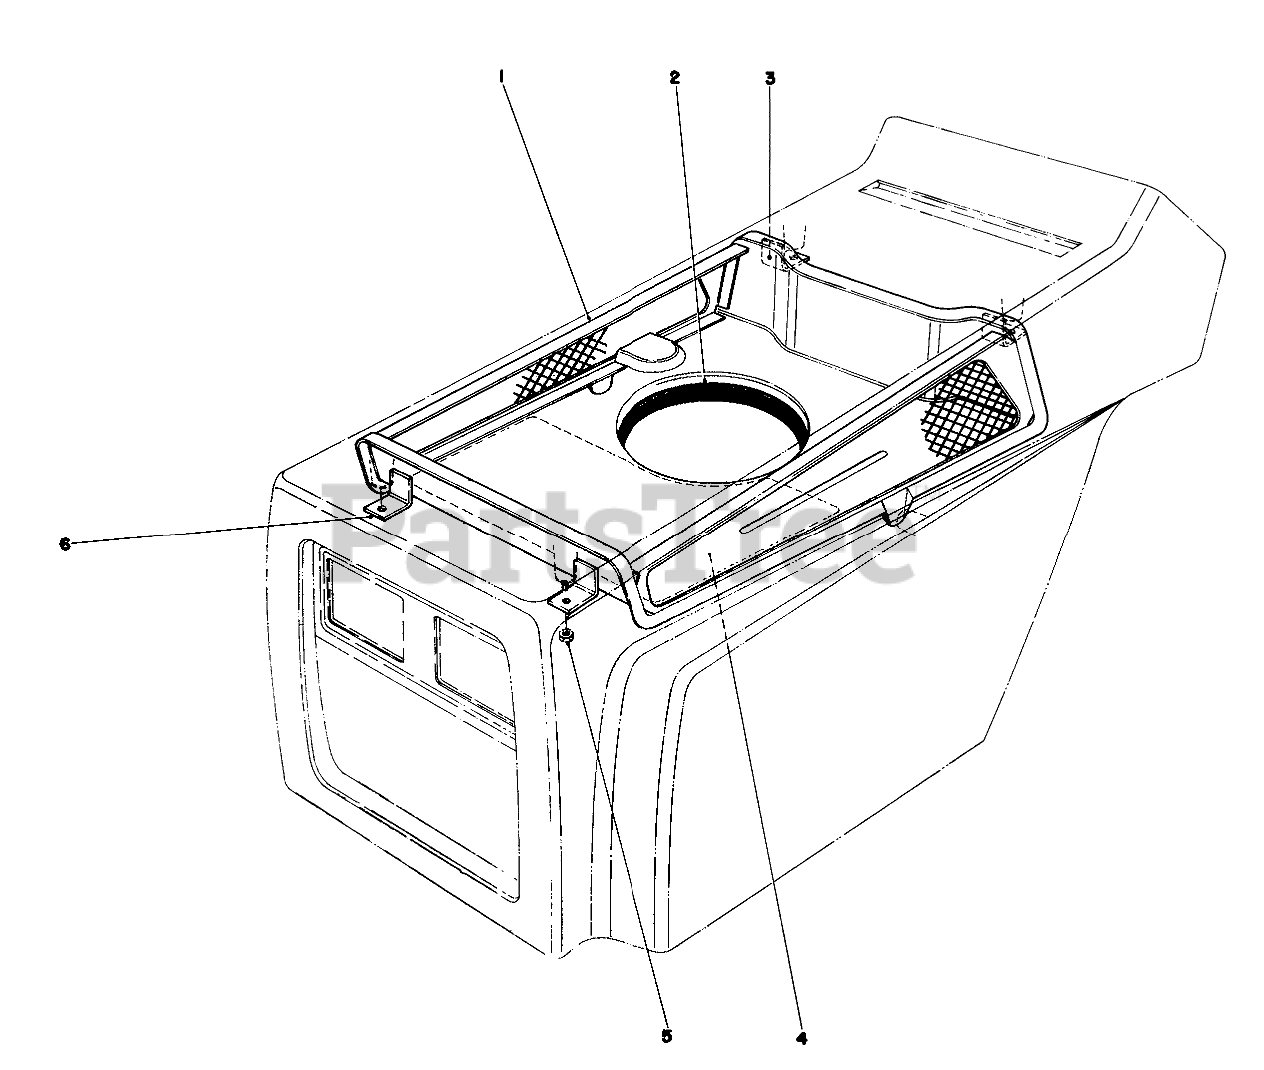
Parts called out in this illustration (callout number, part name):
1	Duct Hood
2	Seal Engine
3	Bracket Rear Duct Support
4	Decal Service
5	NUT-LOCK, NI
6	Bracket Duct Support
